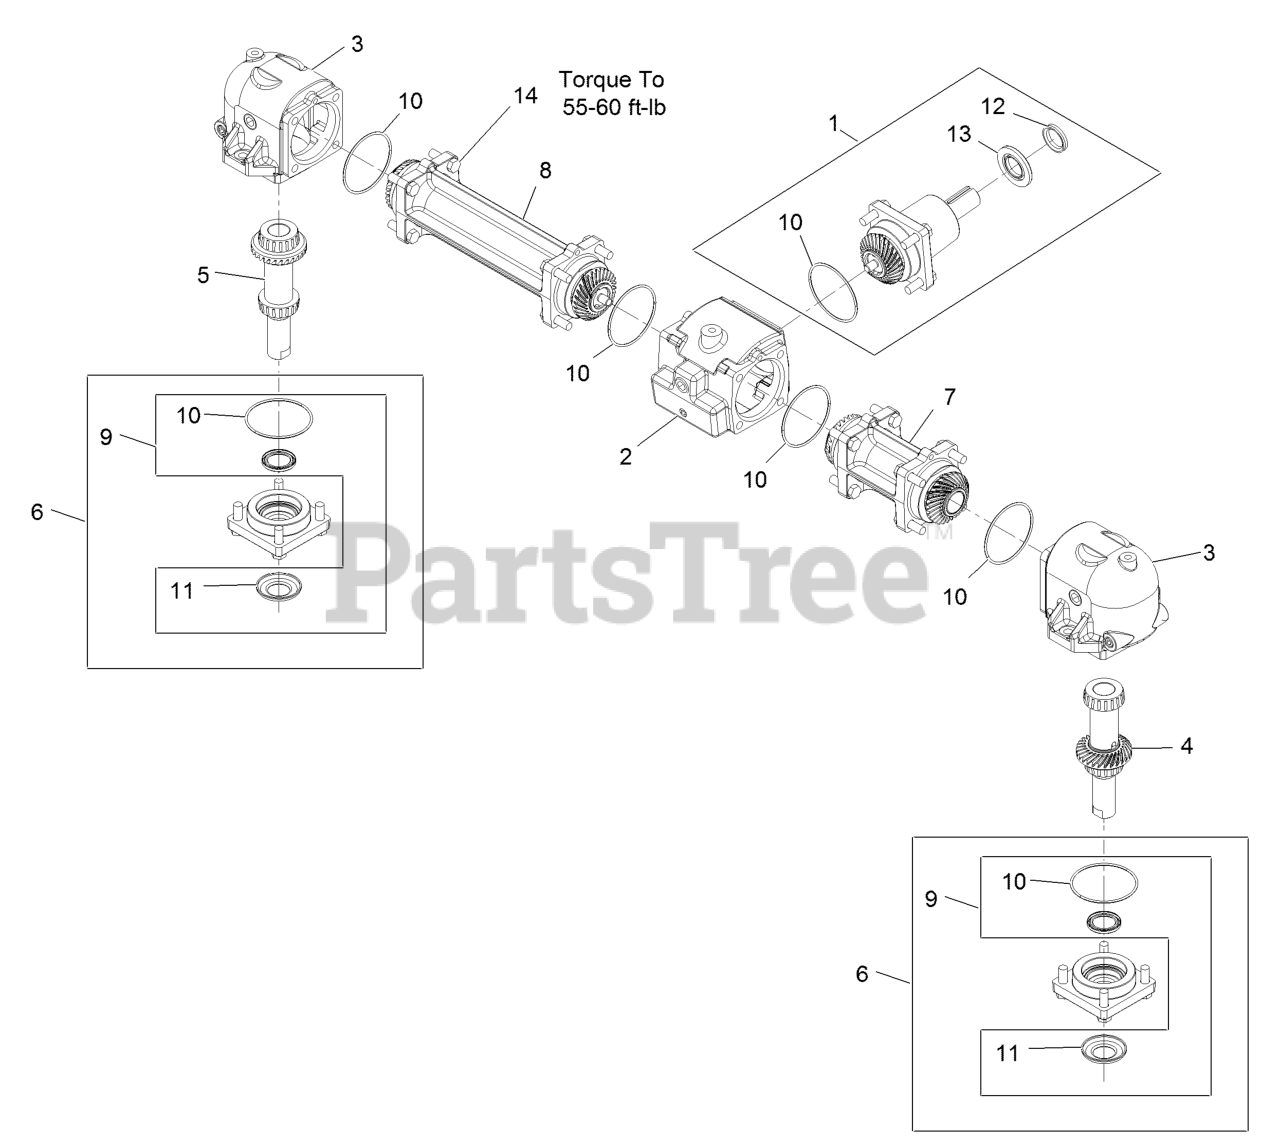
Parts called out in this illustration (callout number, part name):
1	INPUT PINION ASM
2	HOUSING-CENTER
3	HOUSING-END
4	LH OUTPUT SHAFT AND GEAR
5	RH OUTPUT SHAFT AND GEAR
6	CAP-OUTPUT
7	TUBE-CONNECTOR, SHORT
8	TUBE-CONNECTOR, LONG
9	OUTPUT SEAL KIT
10	SEAL-O-RING
11	WASHER-CUPPED
12	SEAL-V-RING
13	SEAL-INPUT
